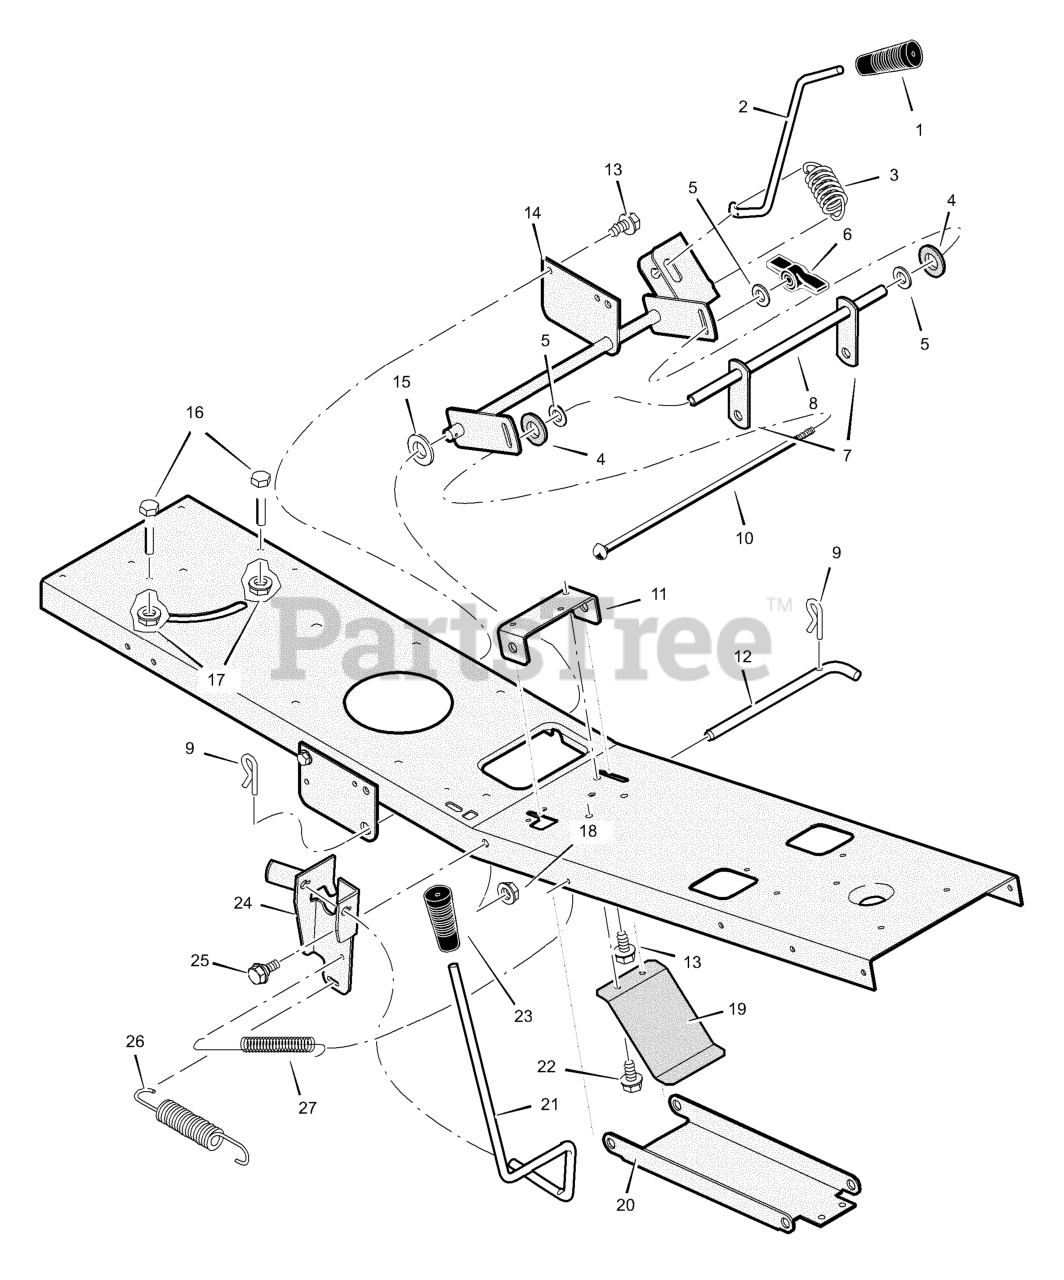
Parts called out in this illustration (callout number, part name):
1	Grip, Lift Lever
2	Lever, Lift
3	Spring, Extension
4	Pad, Friction
6	Wingnut
7	Link, Lift
8	Tube, Spacer
9	Pin, Hair
10	Bolt, Carriage
11	Bracket, Front Hanger Pivot
12	Pin, Front Hanger
14	Arm Assembly, Lifter
15	Washer
16	Screw, Guide
17	Nut, Flange
18	Nut, Flange
19	Spring, Leaf
20	Hanger, Front
21	Lever, PTO
22	Screw
23	Grip, PTO
24	Bracket, PTO
25	Bolt, Shoulder
26	Spring, Extension
27	Spring, Extension
